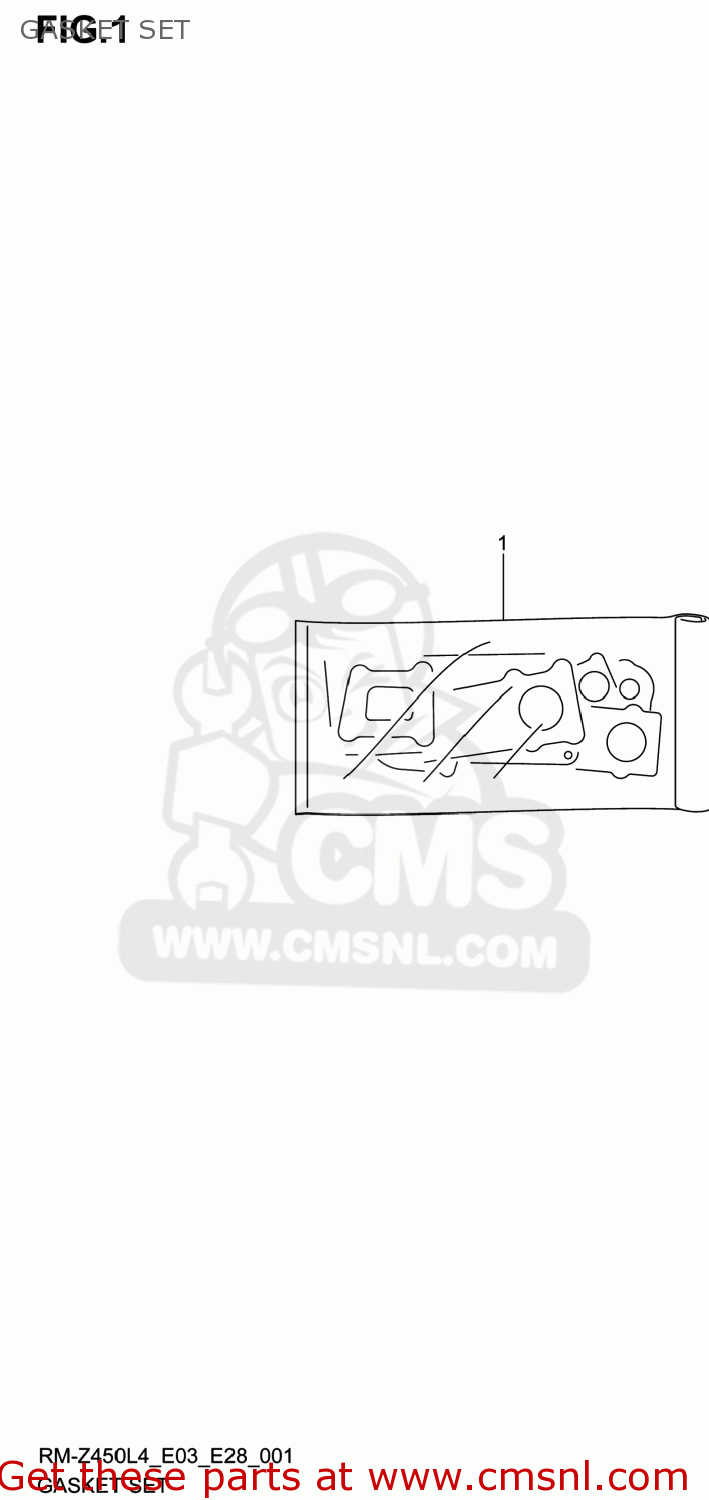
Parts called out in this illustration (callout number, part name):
1	GASKET SET (NAS)
2	GASKET,CYLINDER HEAD (NAS)
3	GASKET,CYL HEAD COVER (NAS)
4	GASKET,CYLINDER (NAS)
5	GASKET,CRANKCASE (NAS)
6	GASKET,CLUTCH COVER (NAS)
7	GASKET,MAGNETO COVER (NAS)
8	GASKET,CLUTCH COVER OUTER (NAS)
9	GASKET,TENSIONER ADJUSTER (NAS)
10	GASKET,EXHAUST PIPE (NAS)
11	O RING,WATER PUMP CASE
